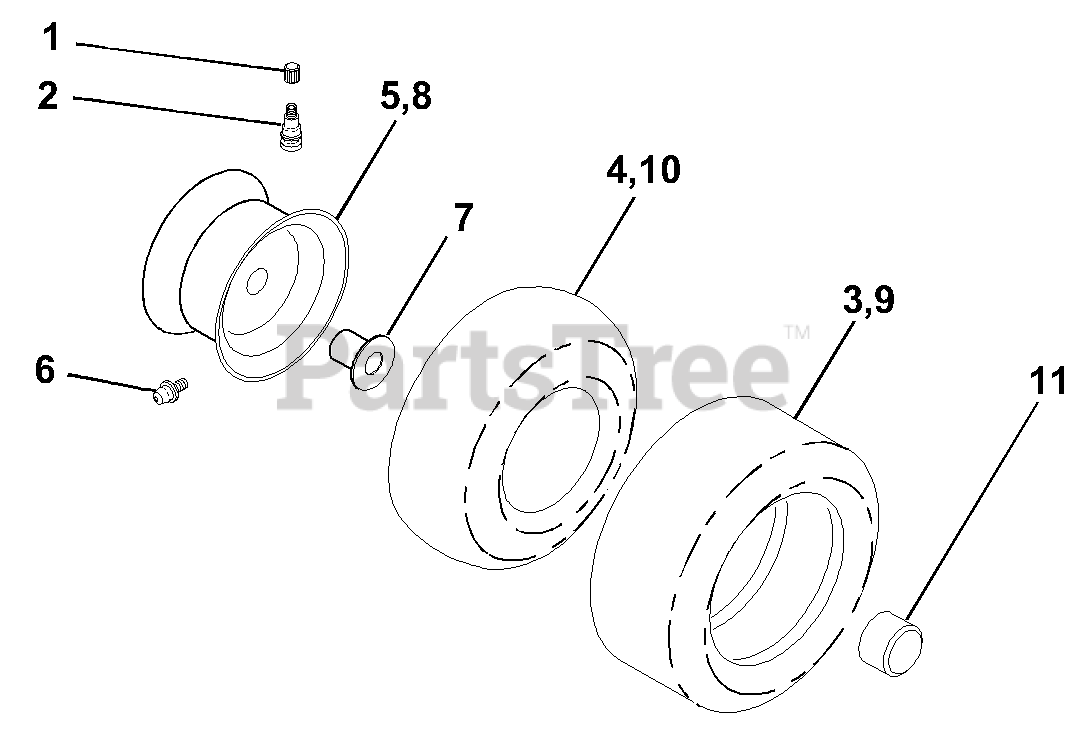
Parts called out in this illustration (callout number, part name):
1	Cap, Tire valve
2	Stem, Valve
3	Tire, Front
4	Tube, Front
5	Rim assembly, 6" front
6	Fitting, Grease
7	Bearing, Flange
8	Rim assembly, 8" rear
10	Tube, Rear
11	Cap, Hub Axle
